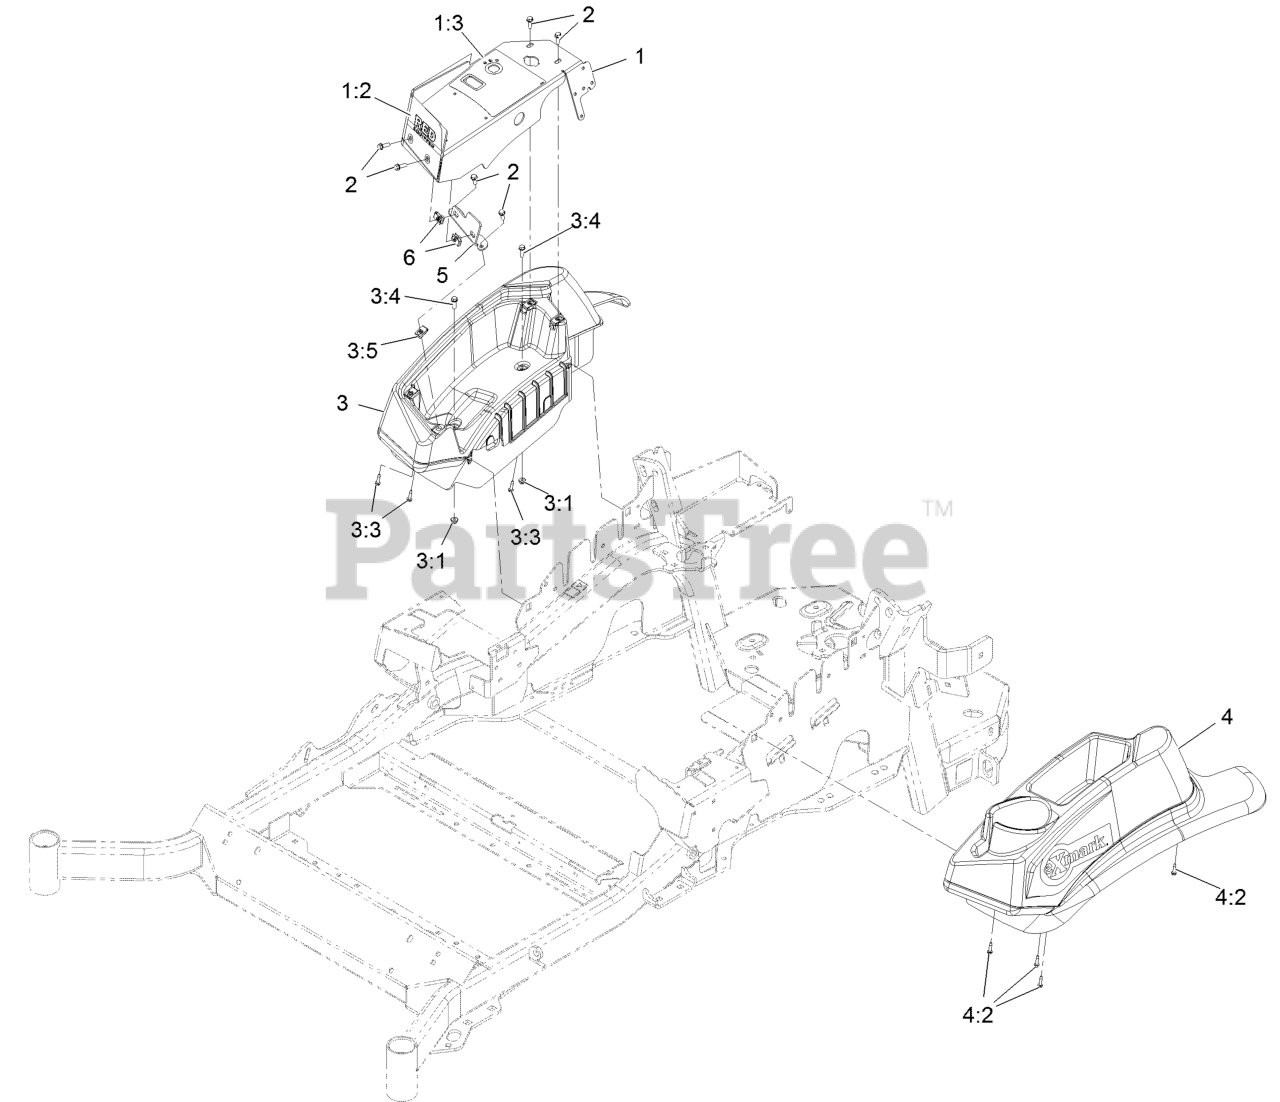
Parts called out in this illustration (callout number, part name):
1	Cover Panel ASM W/Decals
1:2	Decal-Control Panel Red
1:3	Decal-Console
2	Screw-HWH
3	Console,RH Narrow ASM
3:3	Screw,Thd Form,HWH
3:4	Screw-HWH
4	Console.LH Narrow ASM
4:2	Screw,Thd Form,HWH
5	Bracket-Console
